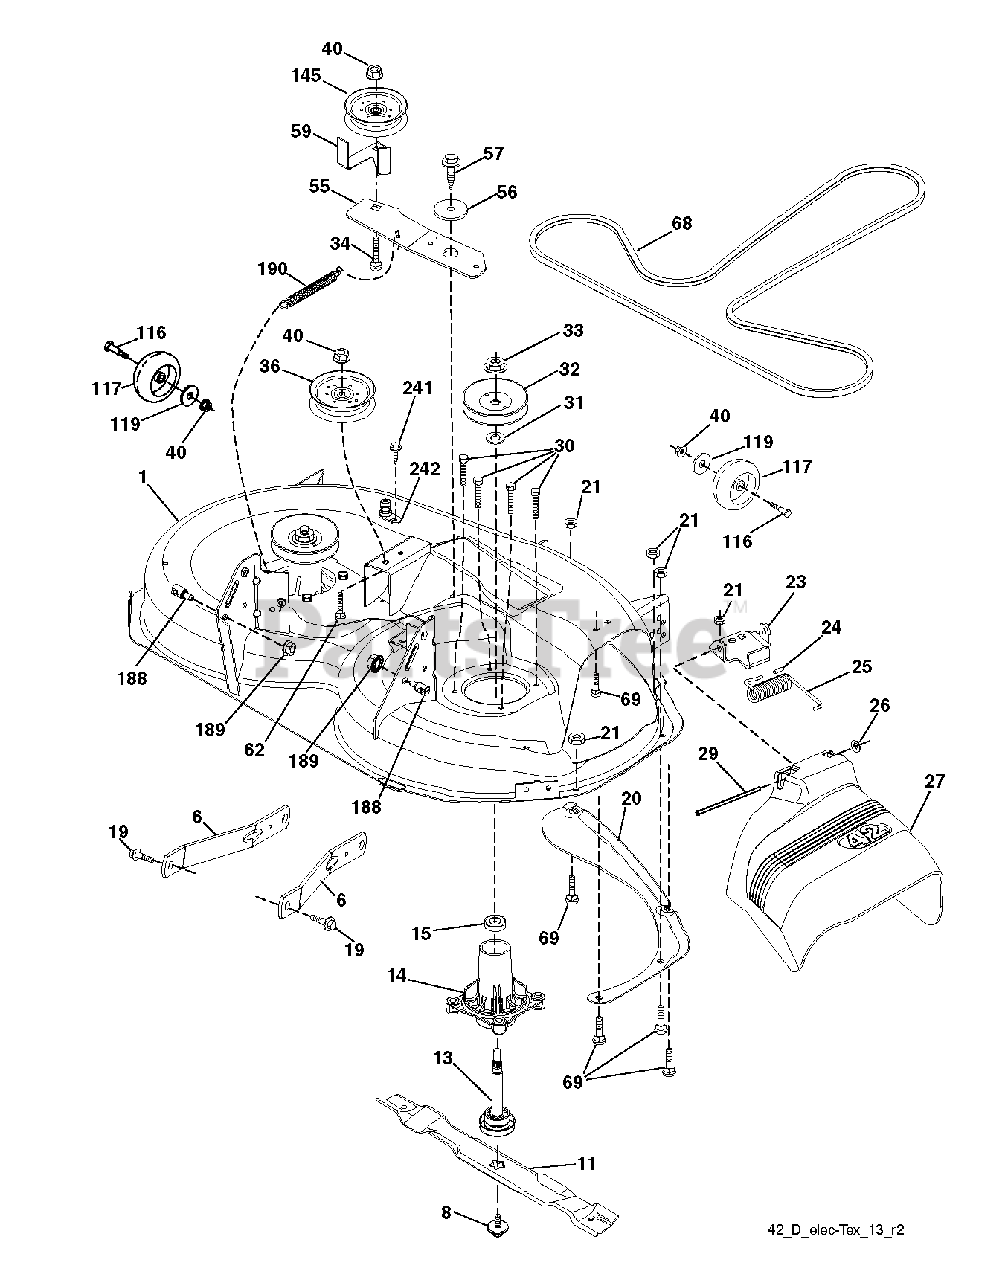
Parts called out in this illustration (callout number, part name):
6	ARM.SUSPENSION.MOWER.R
8	BOLT.WASHER.ASM.7/16-2
11	42" HI-LIFT BLADE
13	SHAFT.ASM.MDRL.N/GREASE.38
14	HOUSING.MANDREL.4PT.
19	BOLT.SHOULDER
20	BAFFLE.VORTEX
21	LOCKNUT
23	BRKT.DEFLECTOR.38"2005+
24	CAP-SLEEVE LT
25	SPRING.TORSION.DEFLECT
26	NUT PUSH M
27	SHIELD.DEFLECTOR.MOWER.42"BLAC
29	ROD.HINGE
30	SCREW, WASHER HEAD
31	WASHER.SPACER.MANDREL
32	PULLEY/MANDREL
33	NUT.FLANGE.LOCK.TOP
34	BOLT.3/8-16X1.50
36	PULLEY.IDLER.2006
40	NUT LOCK FLG 3/8-16 UNC
55	IDLER.ARM.42"
56	SPACER.RETAINER
57	SCREW 3/8-16X1
59	GUARD, BELT
62	BOLT
68	BELT V SECONDARY
69	BOLT
116	BOLT M
117	WHEEL.GAGE.HALF.SPOKED
119	WASHER
145	PULLEY.IDLER.48"PRIMARY
188	STUD.FASTNER.W/ANTI-ROTATE
189	NUT LOCK HEX FLANGE 5/16-18
190	SPRING.MOWER.DRIVE.ELECTRIC
241	SCREW.TT.#10-32X.5.3/8.FLANGE
242	PORT.WASHOUT
